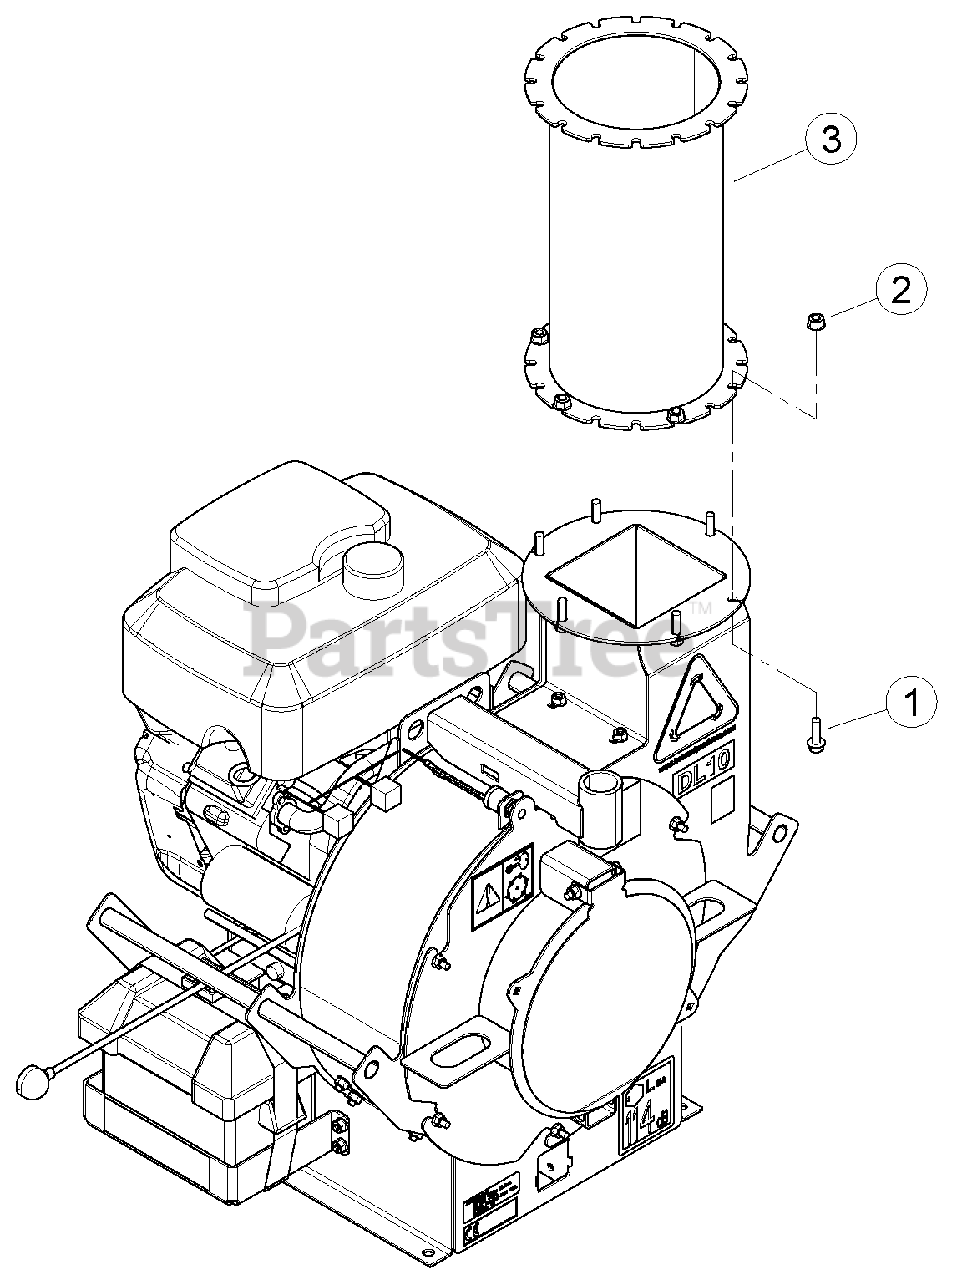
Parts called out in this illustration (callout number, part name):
1	BOLT, 3/8 X 1-1/4 FLANGE NC
2	NUT, 3/8-16 NYLOCK FLANGE
3	WELDMENT, CHUTE EXTENSION
